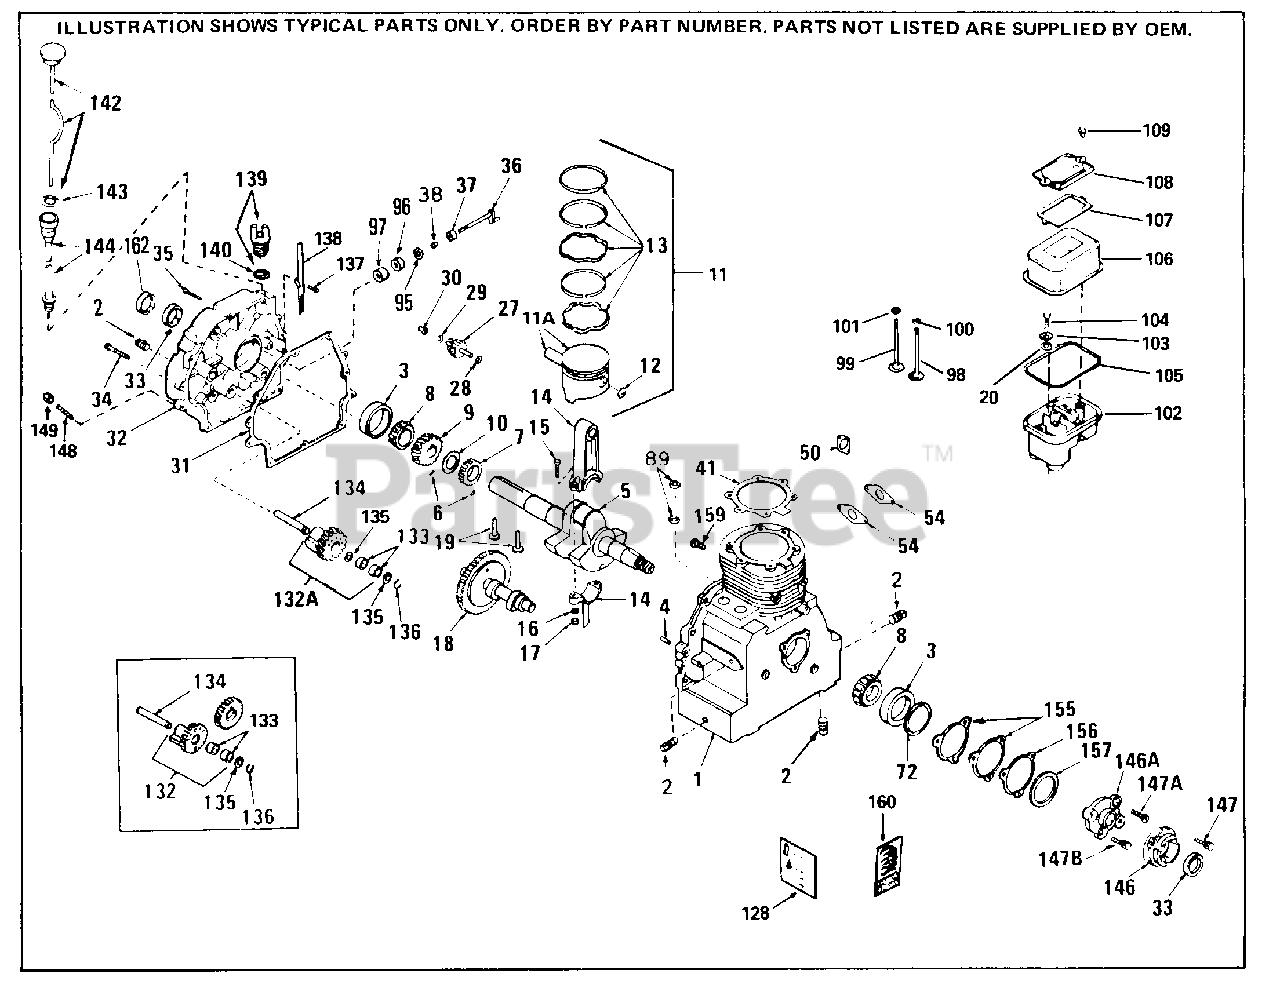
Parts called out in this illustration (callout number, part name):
1	"Cylinder (Incl. 2, 4 & 33)
2	Pipe Plug (Sq.head, 1/8-27) Use as re quired
2	Oil Drain Plug (3/8-18) uired)
2	Oil Drain Plug As req.)
2	Pipe Plug (Sq.head, 3/8-18) Use as re quired
3	Cup, Bearing
4	Dowel Pin
5	Crankshaft Incl. 3, 6 thru 10 & 132A
6	Pin, Crankshaft gear
7	Gear, Crankshaft
8	Bearing, Tapered roller
9	Gear, Counterbalance (Helical teeth)
11	Piston, Pin & Ring Set (Std.) 3-5/8" Bore
11	Piston, Pin & Ring Set (.010" OS)
11	Piston, Pin & Ring Set (.020" OS)
11A	Piston & Pin Ass'y. (Incl. 12) (Std.) (3-5/8")
11A	Piston & Pin Ass'y. (Incl. 12) .010" OS
11A	Piston & Pin Ass'y. (Incl. 12) .020" OS
12	Pin, Piston pin retaining
13	Ring Set (Std.) (3-5/8" Bore)
13	Ring Set (.010" OS)
13	Ring Set (.020" OS)
14	Connecting Rod Assy. (Incl. 15, 16 & 1 7)(Std.)
14	Connecting Rod Assy. (Incl. 15,16,17) . 010" US
14	Connecting Rod Assy. Incl. 15, 16 & 1 7
15	Bolt, Connecting rod
18	Camshaft (MCR)
19	Lifter, Valve
20	"O" Ring
27	Gear & Shaft Assy., Governor
28	Washer, Flat
29	WASHER
31	Gasket, Cylinder cover
32	Cover Assy., Cylinder Incl. 2, 33 & 1 34
33	Seal, Oil
34	Screw, 1/4-20 x 1"
35	Screw, 1/4-20 x 2-1/4"
36	Rod Assy., Governor
37	Spacer, Governor rod
38	Retaining Ring
41	Gasket, Cylinder head
50	Gasket, Intake pipe
54	Gasket, Carburetor
72	"O" Ring
89	"O" Ring
98	Intake Valve (Std.) Not incl. w/short block
99	Exhaust Valve (Std.) Not incl.w/short block
100	"O" Ring (Intake only)
101	"O" Ring (Exhaust only)
102	Housing Rocker arm Not incl. w/short block
103	Washer Not included with short block
104	Screw (Not included with short block)
105	"O" Ring
106	Cover, Rocker arm Not incl. w/short b lock
107	Gasket, Breather
108	Breather Body Ass'y. Not incl. w/shor t block
109	Screw, 10-32 x 5/8"
128	Decal, Instruction
132A	Weight Assy., Counterbalance (Helical teeth) (Incl. 2 of 133)
133	Bearing, Needle
134	Shaft, Counterbalance
135	Washer, Thrust
136	Ring, Retaining
137	Screw, 10-24 x 7/8"
138	Tube Extension, Oil fill
140	Oil Fill Plug Gasket
146	Cover, Cylinder NOTE: Determine the gap between the cover and the machine d surface on the cylinder, which can be up from .001" up to .007", in whic h case no shim gaskets will be requir ed. Use of gaskets must be limited t o a combined total of .0
147	Screw, 5/16-18 x 7/8"
148	Nipple, Pipe
149	Cap, Pipe
155	Gasket, Shim (.004/.005 thick) NOTE: Determine the gap between the cover and the machined surface on the cylin der, which can be up from .001" up to .007", in which case no shim gaskets will be required. Use of gaskets mu st be limited to a combined
156	Gasket, Shim (.005/.007 thick) NOTE: Determine the gap between the cover and the machined surface on the cylin der, which can be up from .001" up to .007", in which case no shim gaskets will be required. Use of gaskets mu st be limited to a combined
157	Spacer, Steel (.010 thick) NOTE: Det ermine the gap between the cover and the machined surface on the cylinder, which can be up from .001" up to .00 7", in which case no shim gaskets wil l be required. Use of gaskets must b e limited to a combined
159	Screw, 10-24 x 1/2" (Use as required)
160	Decal, Name
